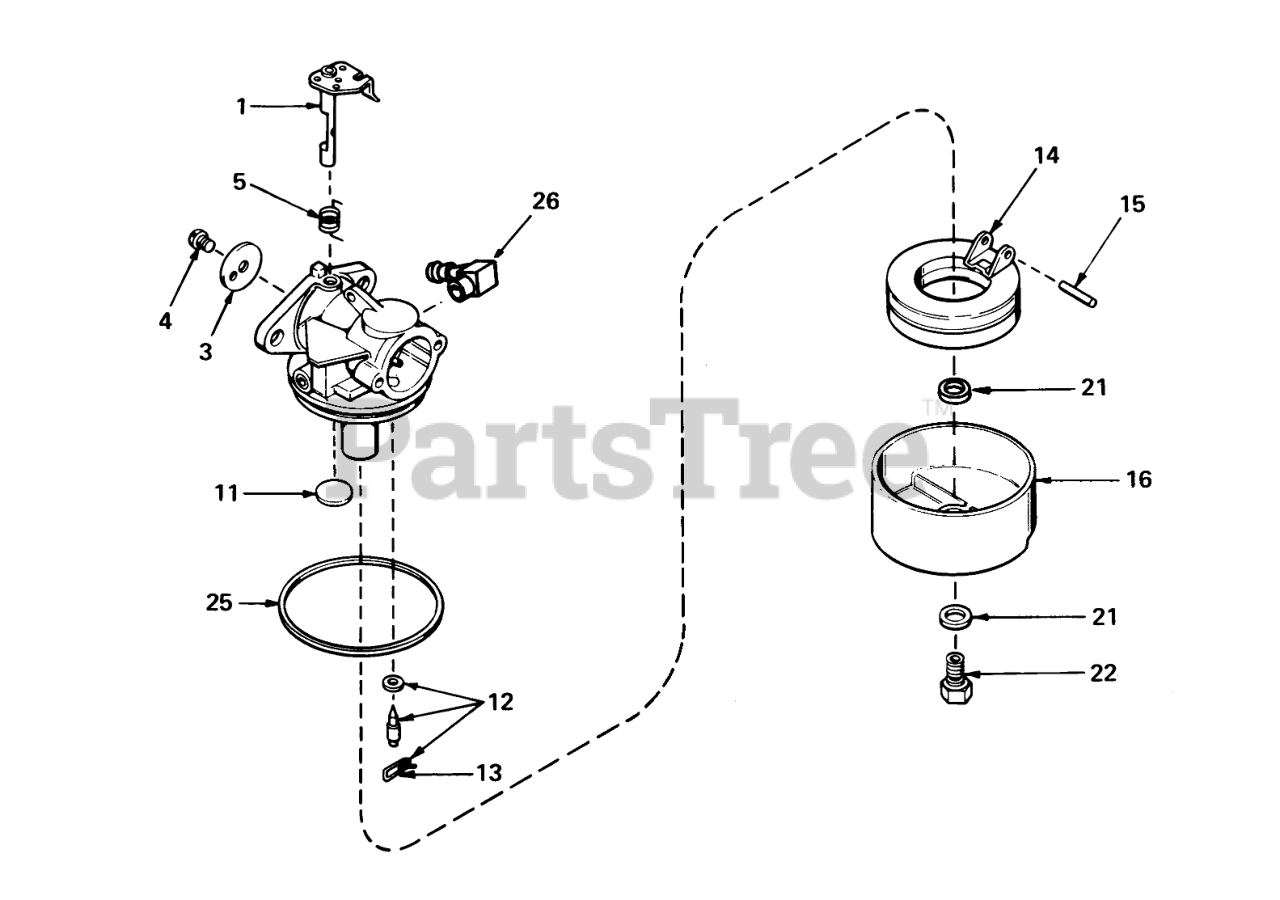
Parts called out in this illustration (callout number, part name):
1	Throttle Shaft and Lever ASM
3	Throttle-Shutter
4	Screw-Shutter
5	Spring, Return
11	Plug-Welch, Atmospheric Vent
12	Inlet Needle, Seat & Clip Assy., (Incl. Ref. #13)
13	Clip-Spring
14	Float,Carburetor
15	Shaft-Float
16	Bowl Float
21	Gasket-Bowl
22	Nut, Float Bowl
25	O Ring-Bowl, Float
26	Fitting-Fuel
